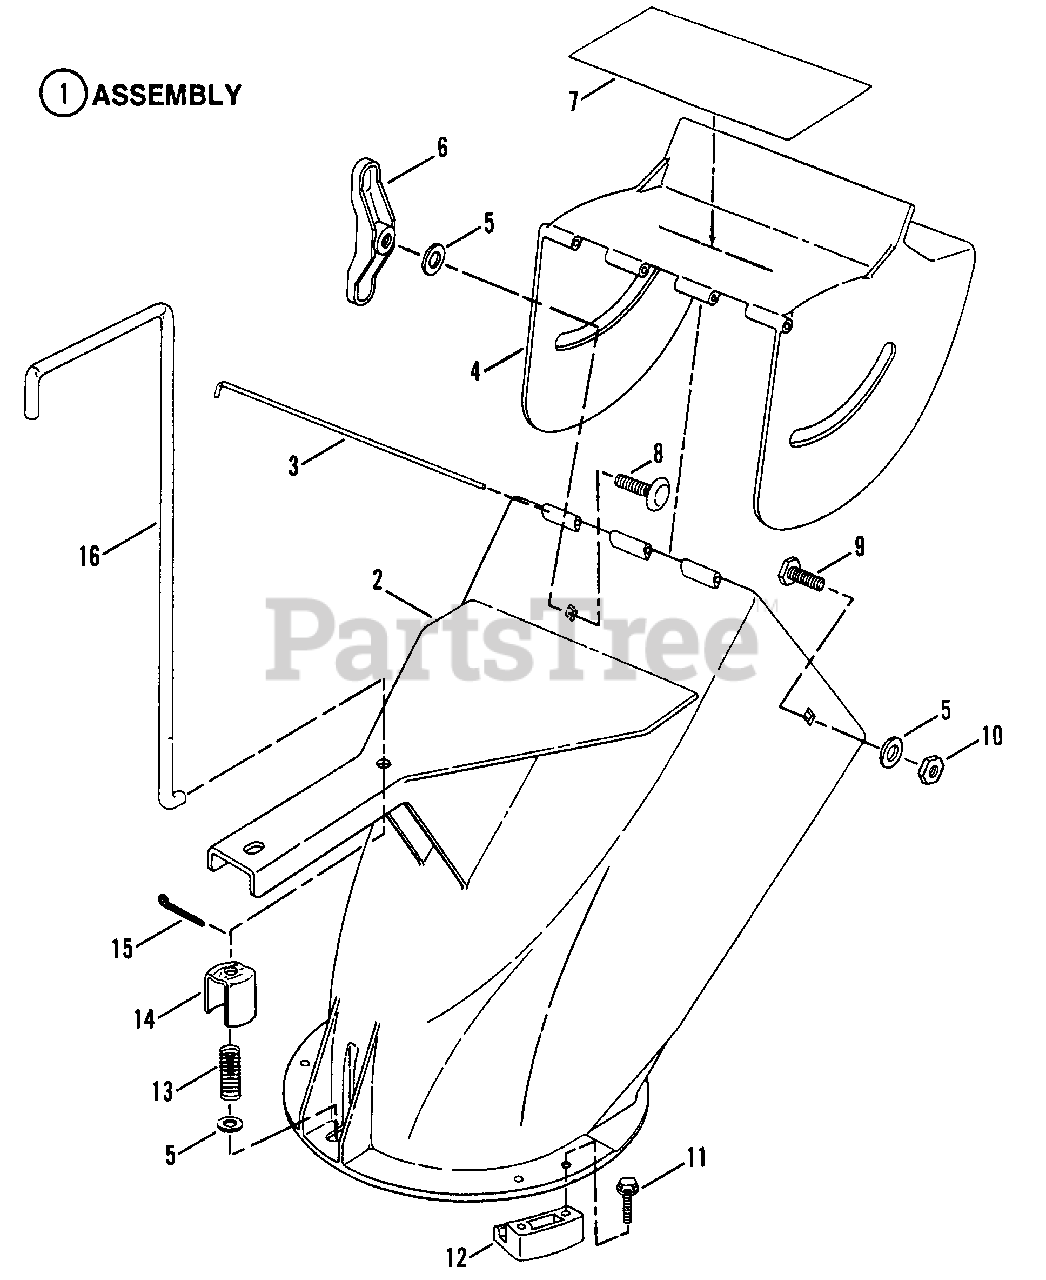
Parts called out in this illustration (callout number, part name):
1	ASSEMBLY, Chute & Discharge Decal
2	CHUTE (Replaced by 7053488)
3	PIN, Wire Hinge
4	DEFLECTOR, Discharge
5	WASHER, 5/16 Flat
6	WING-NUT, 5/16-18
7	DECAL, DANGER
8	BOLT, 5/16-18 x 1" Carriage
9	SCREW, 5/16-24 x 1" Hex Head Cap
10	NUT, 5/16-24 Hex Center Lock
11	SCREW, #10-24 x 5/8" Slotted Hex Head, Self-Tapping
12	RETAINER, Chute to Housing
13	SPRING, Release Rod
14	STOP, Handle
15	COTTER-PIN, 3/32 x 3/4"
16	ROD, Release
